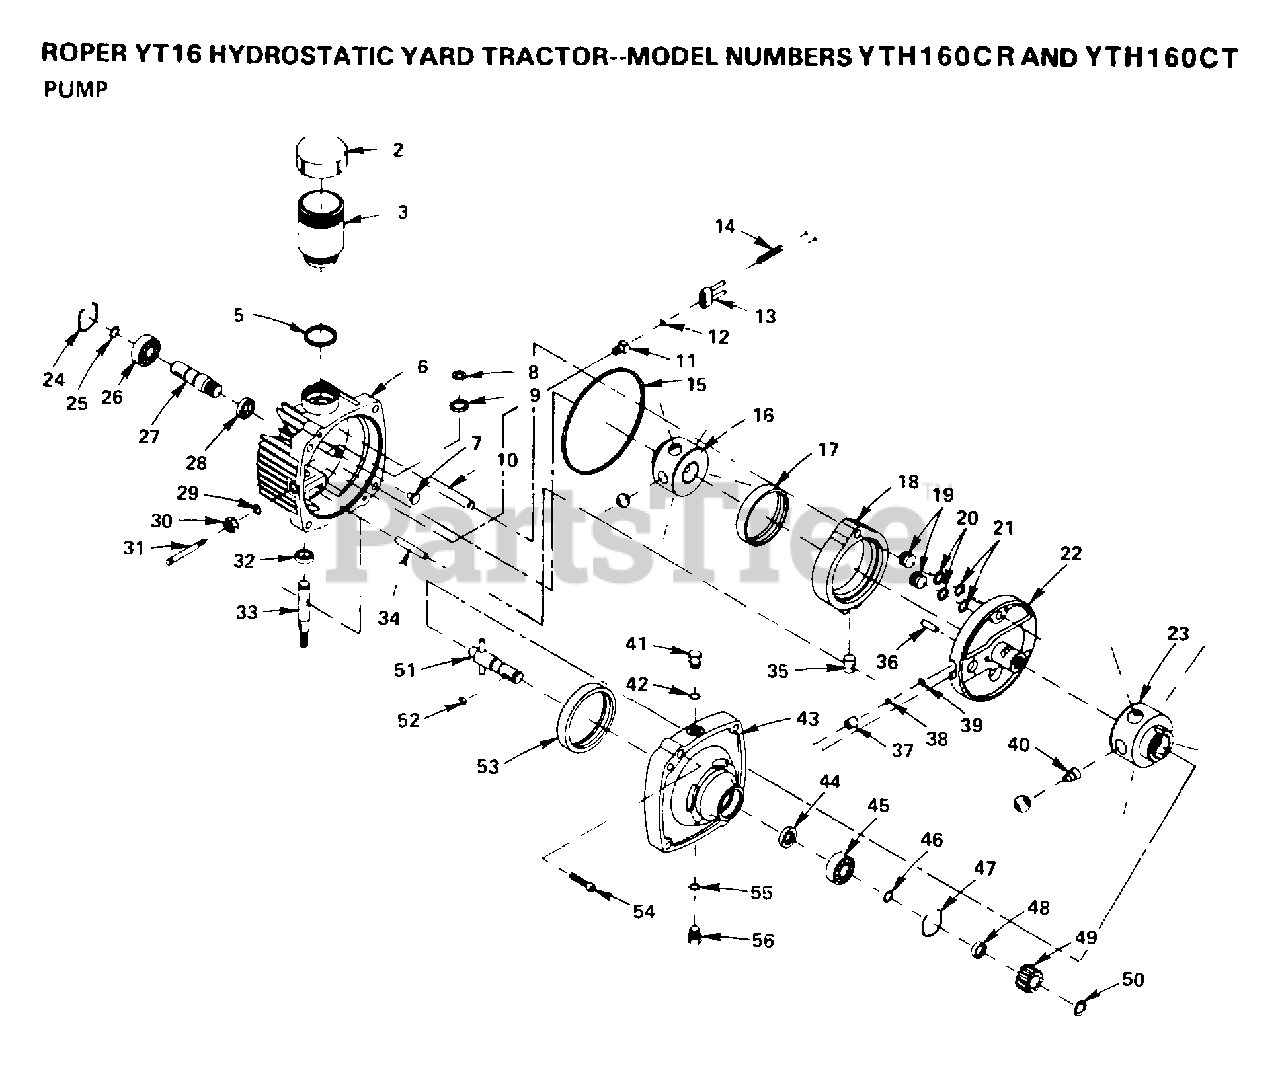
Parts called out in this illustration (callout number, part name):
2	RESERVOIR CVR HYT
3	RESERVOIR BDY HYT
5	SEAL RING HYT
8	RETAINING RING
11	GUIDE FITTING HYT
15	SEAL RING HYT
16	PUMP ROTOR HYT
17	PUMP RACE HYT
19	PISTON HYT
27	INPUT SHAFT HYT
29	O RING HYT
30	NUT&GASKET AS HYT
31	SHAFT DUMP HYT
33	CONTROL SHAFT
37	VALVE BODY HYT
39	RETAINER RING HYT
45	"HYT, BEARING"
47	RETAINER RING HYT
50	RETAINER RING HYT
51	OUTPUT SHAFT
52	KEY HYT
53	MOTOR RACE HYT
54	CAP SCREW HYT
